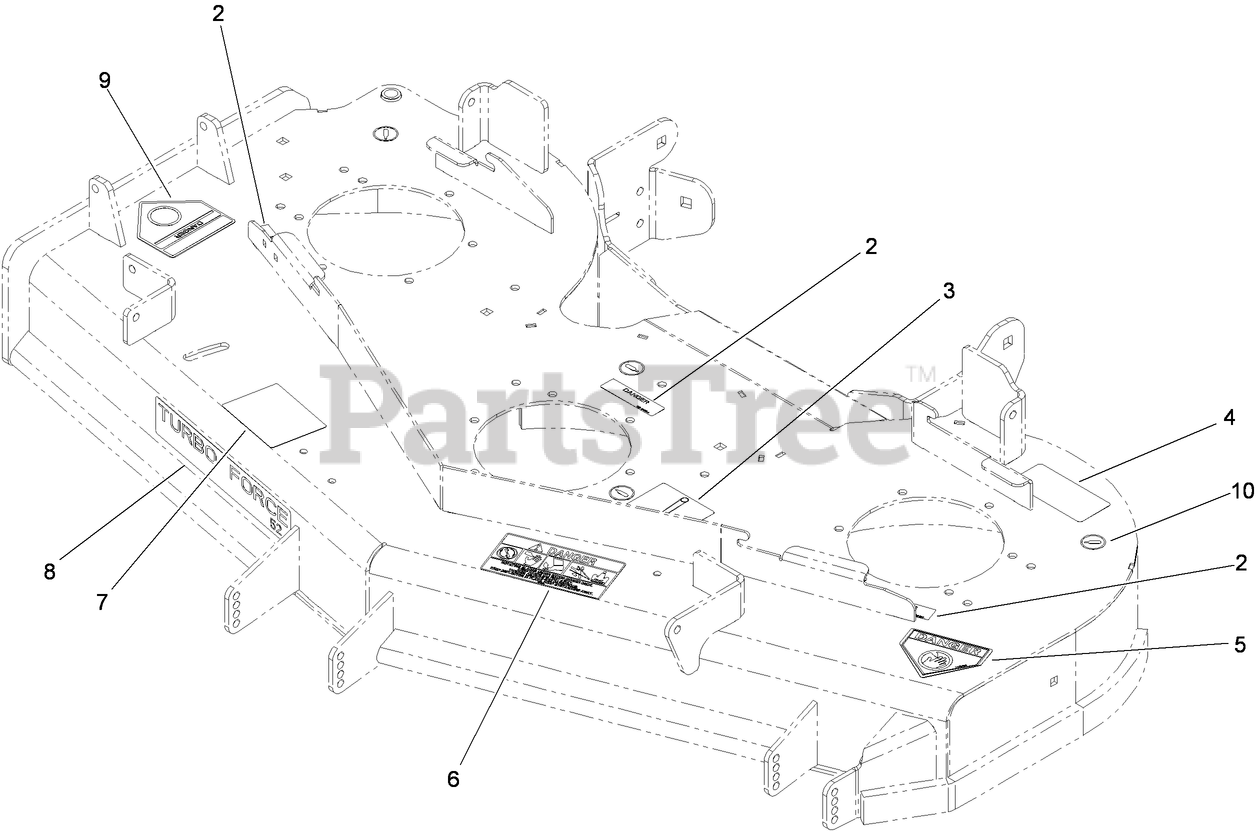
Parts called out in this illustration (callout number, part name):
2	DECAL-COVER, MISSING
3	DECAL-ROUTING, DECK BELT
4	DECAL-TORQUE
5	DECAL-DANGER
6	DECAL-DANGER, THROWN OBJECT
7	DECAL-SCALP, ANTI
9	DECAL-DANGER
10	DECAL-GREASE
